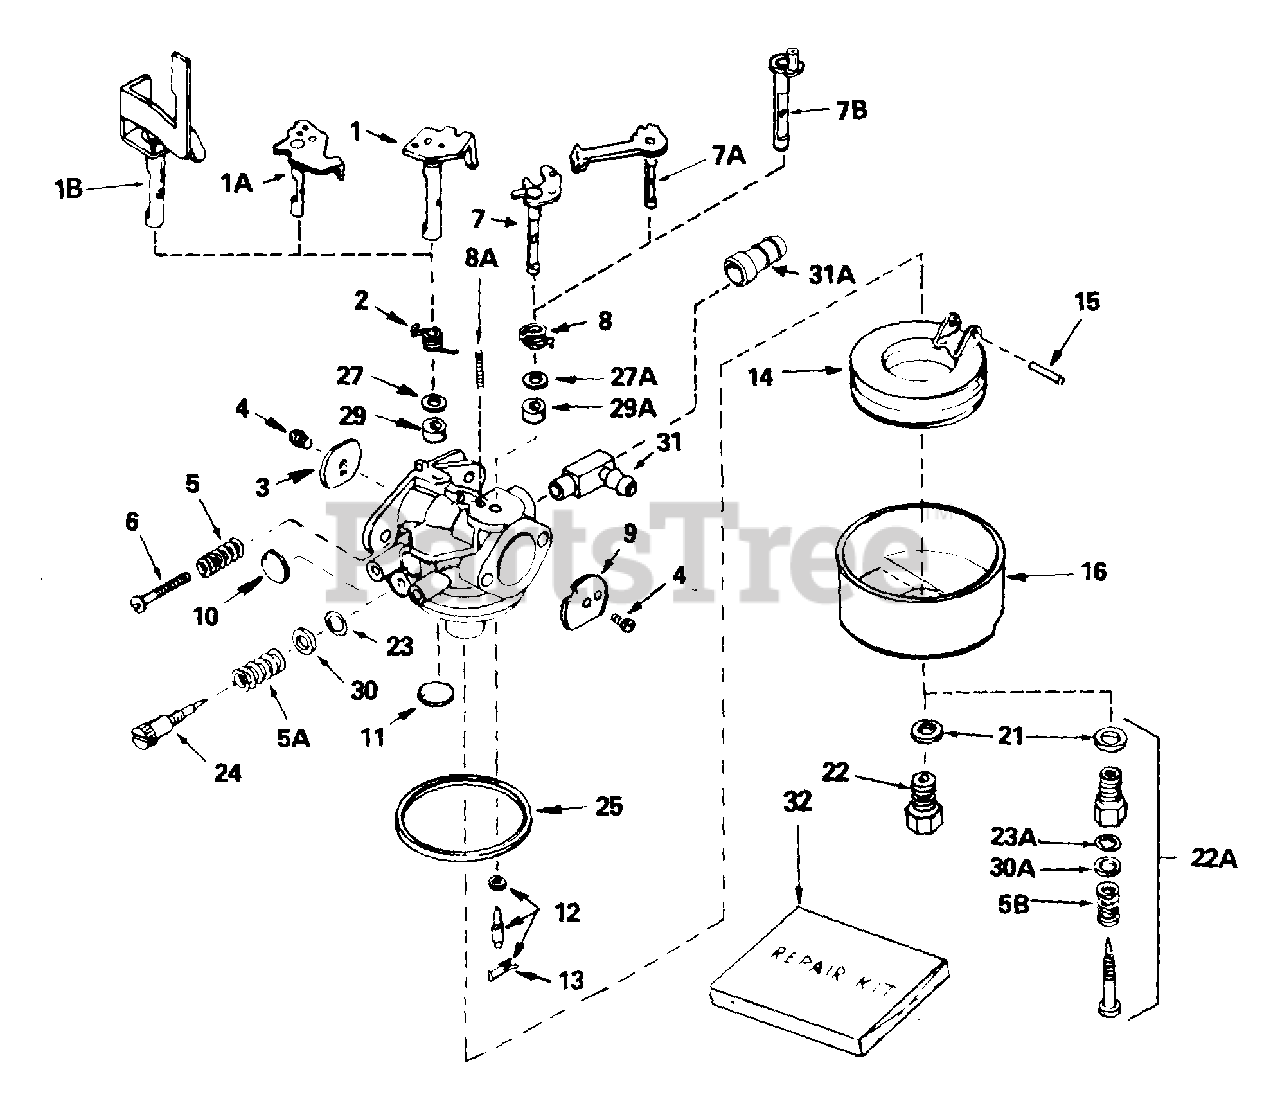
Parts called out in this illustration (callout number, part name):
1	"Shaft & Lever Assy., Throttle
2	Spring, Throttle return
3	Shutter, Throttle
4	Screw, Throttle & Choke shutter
5	Spring, Adj.
5A	Spring, Adj. screw
6	Screw, Idle regulating
7	Shaft & Lever Assy., Choke
8	Spring, Choke return
9	Shutter, Choke
10	Plug, Welch
11	Plug, Welch
12	Inlet Needle, Seat & Clip Assy.
13	Clip, Inlet needle
14	Float, Carburetor
15	Shaft, Float
16	Bowl, Float
21	Gasket, Bowl-to-body
22	Nut, Float bowl (.041)
23	"O" Ring, Adj. screw
24	Screw, Idle adj.
25	Gasket, Bowl-to-body
29	Seal, Dust
29A	Seal, Dust
30	Washer, Flat
31	Fitting Assy., Fuel
